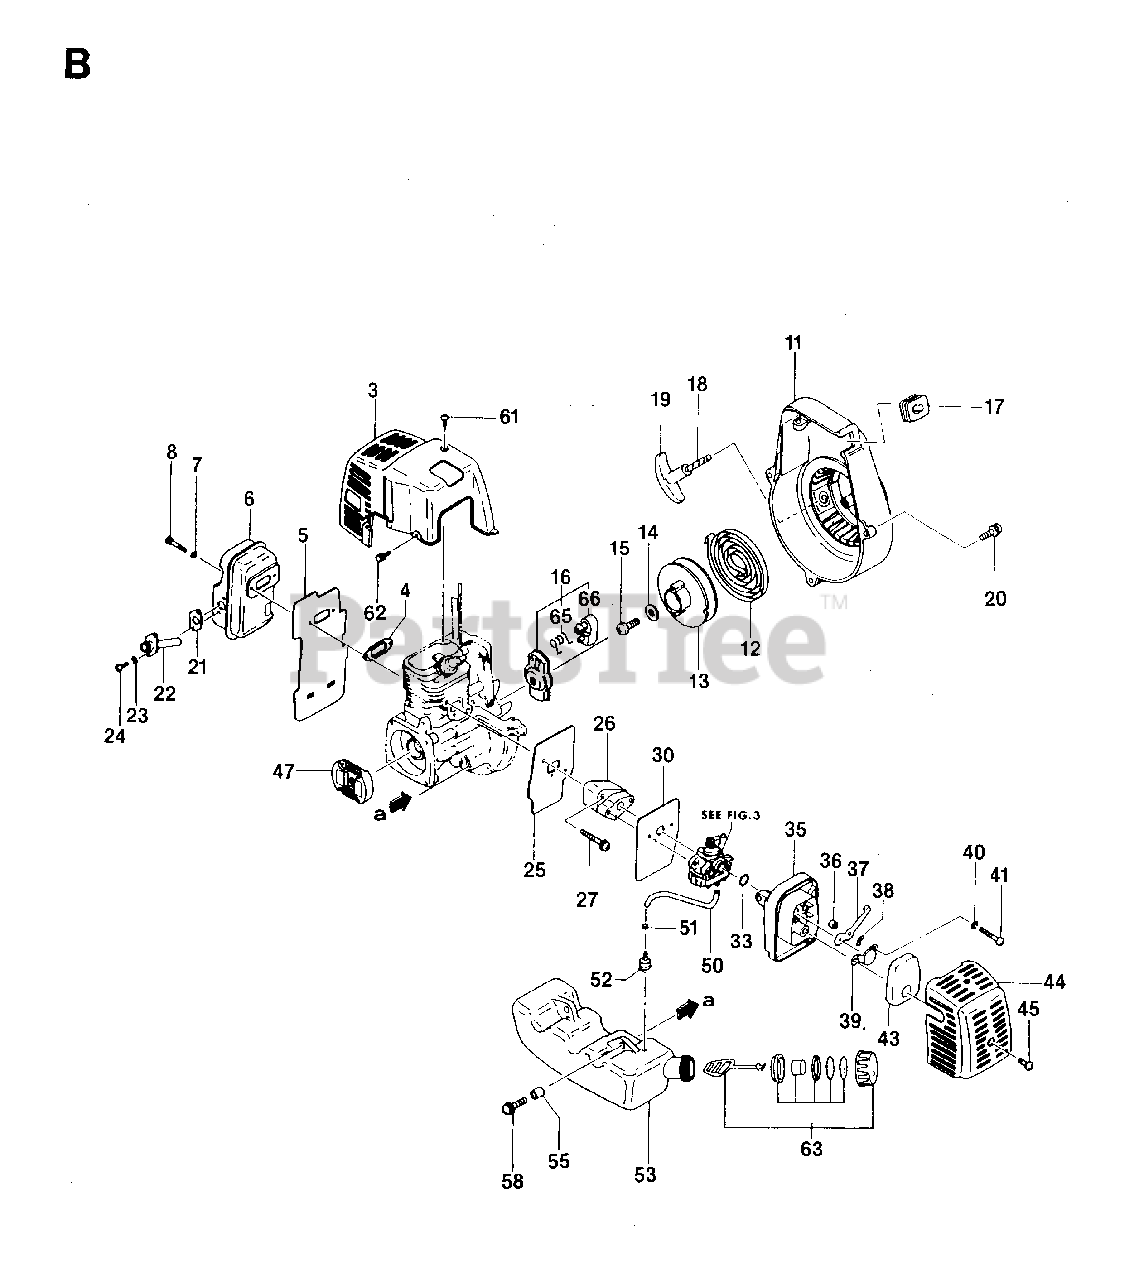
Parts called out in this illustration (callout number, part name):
7	WASHER 5.3X12
8	SCREW MC6S 5X50
23	SPRING WASHER 4.1X7.1
24	SCREW MC6S 4X8
40	SPRING WASHER
41	SCREW MC6S 5X60
